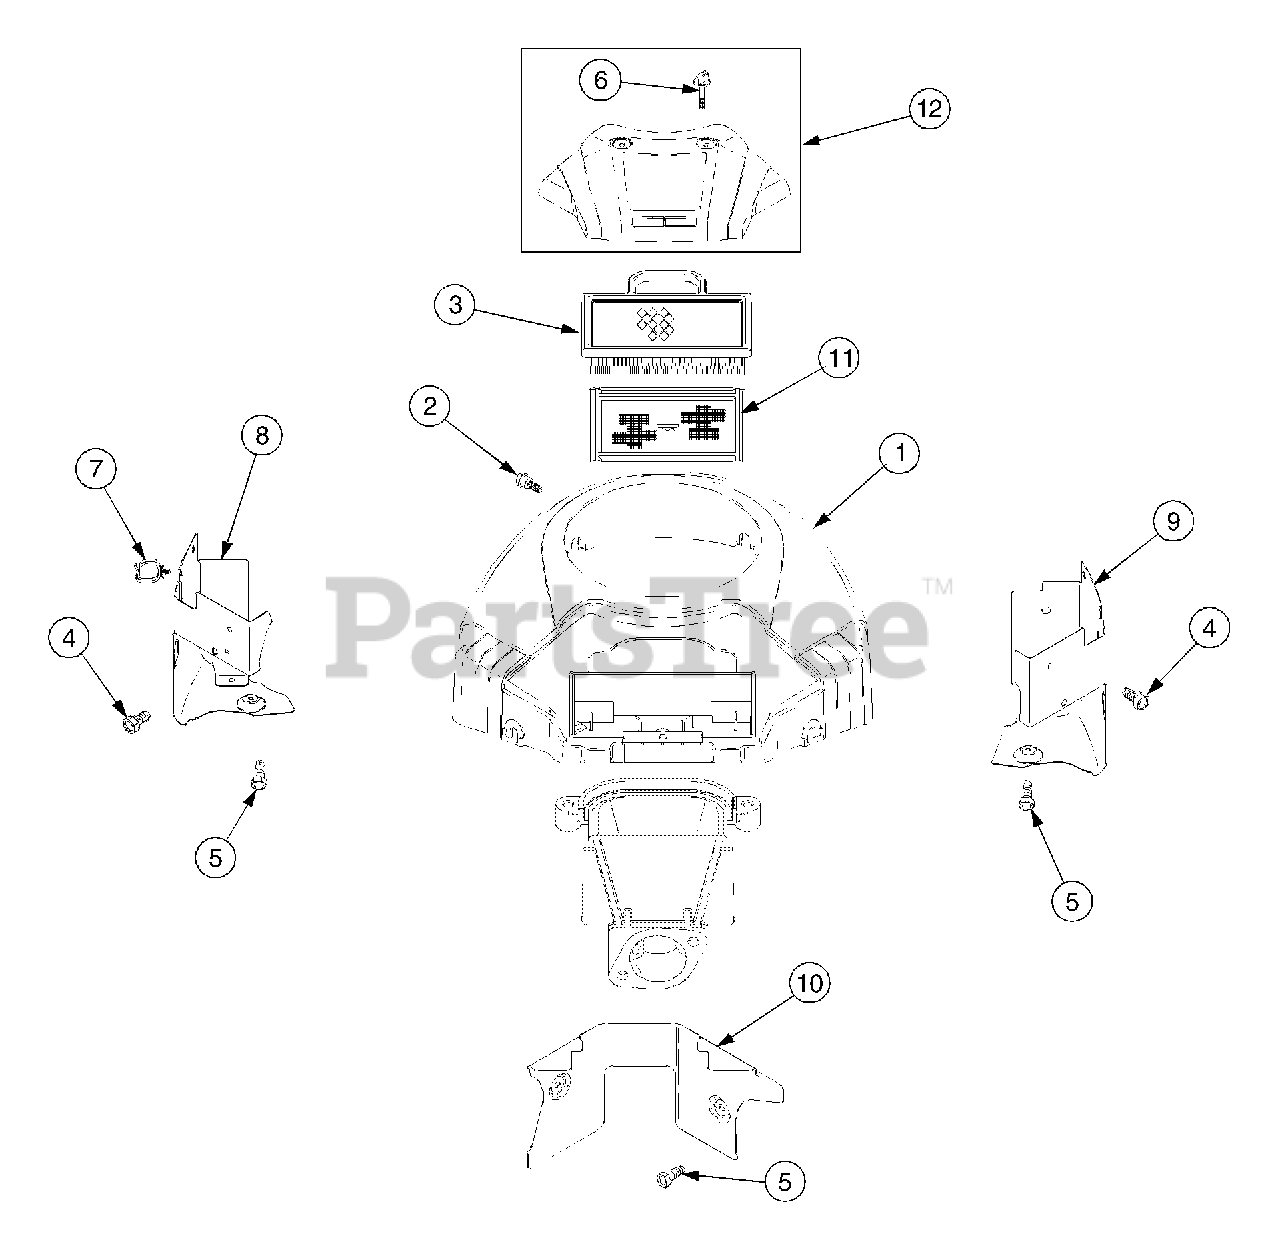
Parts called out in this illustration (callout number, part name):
1	Housing, Blower
2	Screw (Blower Housing)
3	Filt er, Air Cleaner Cartridge
4	Screw (Air Guide Cover)
5	Screw (Air Guide Cover)
6	Knob, Air Cleaner
8	Cover, Air Guide
9	Cover, Air Guide
10	Cover, Air Guide
11	Filter, Pre Cleaner
12	Cover, Air Cleaner
